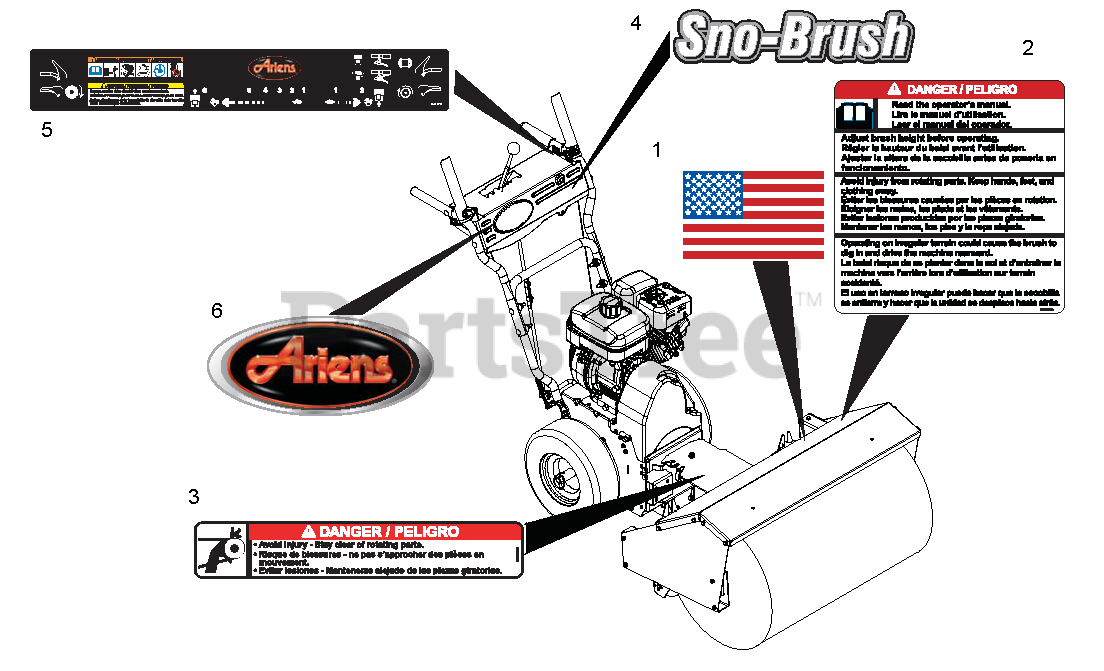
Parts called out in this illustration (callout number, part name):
1	DECAL, AMERICAN FLAG
2	DECAL, DANGER - POWER BRUSH
3	DECAL- DANGER
4	DECAL,SNO-BRUSH
5	DECAL, CONTROL, SNO-BRUSH 920
6	DECAL, ARIENS JEWEL
